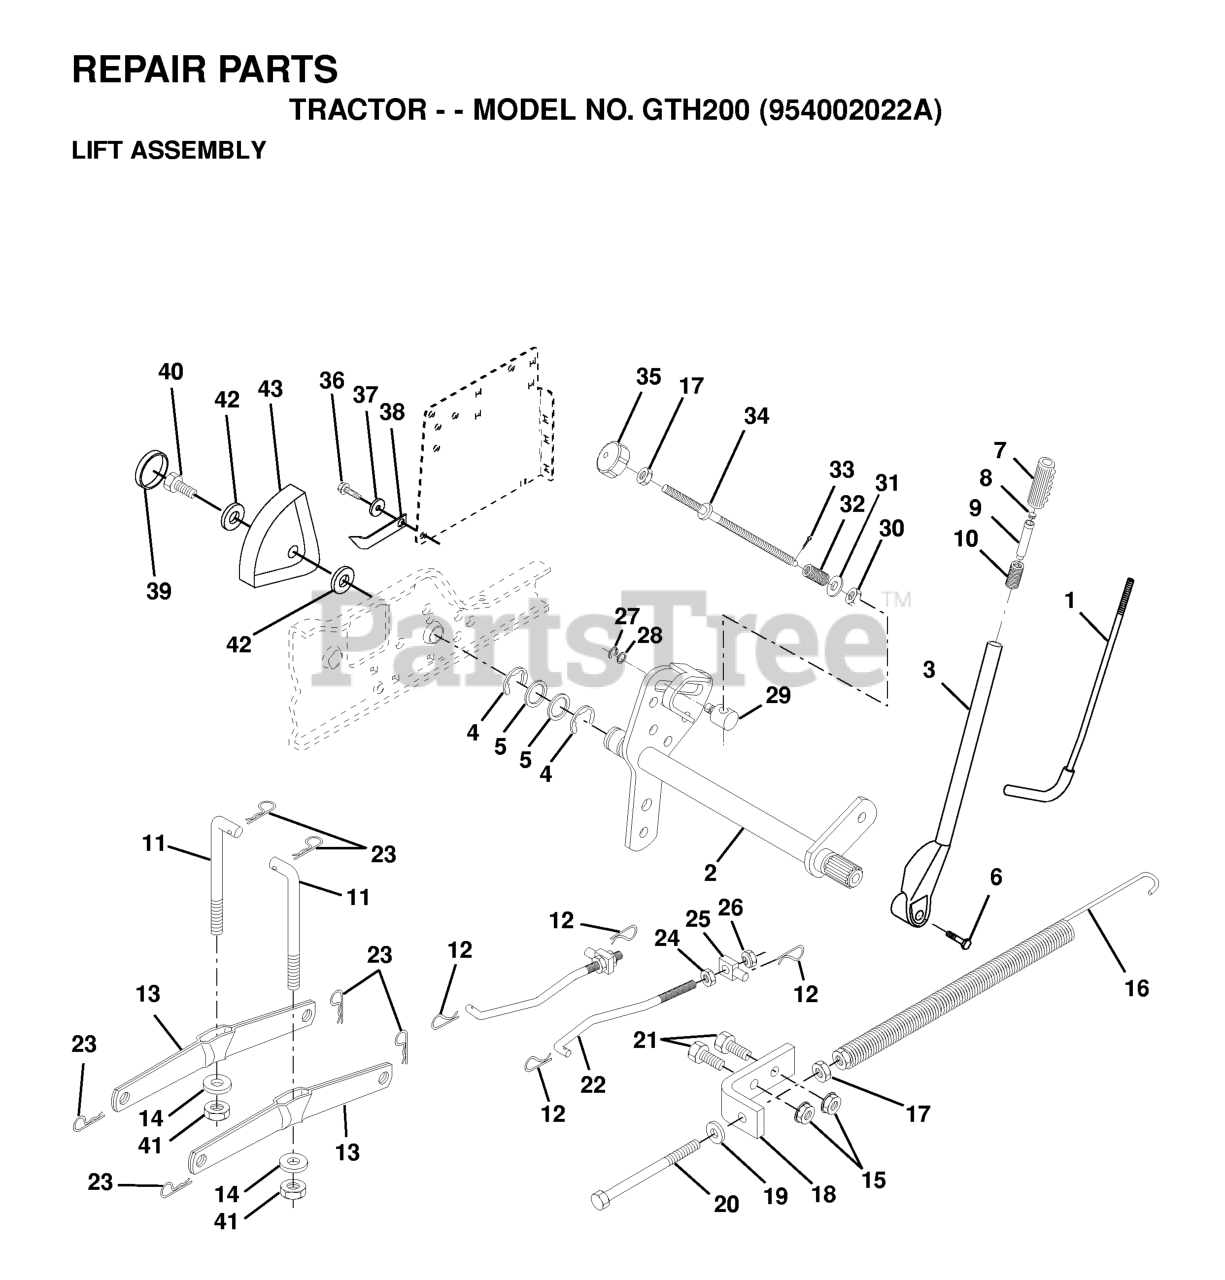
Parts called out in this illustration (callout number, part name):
1	LEVER ROD LT
2	SHAFT ASM, LIFT VGT
3	LIFT LEVER KIT
5	Washer 29/32 x 1 - 1/4 x 16 Ga.
6	BOLT
7	GRIP HANDLE
8	PLUNGER BUT KIT
9	PLUNGER BUT KIT
10	SPRING**
11	LINK LIFT
12	SPRING RETAINER
13	ARM.REAR.SUSPENSION
14	BEARING PIVOT
15	NUT
16	LIFT SPRING
17	NUT
19	WASHER
21	BOLT
22	FRONT LINK
23	RETAINER-SPRNG RB
24	NUT.HEX.JAM.1/2-13
25	TRUNION
26	NUT.LK.W/WSH.1/2.
27	Ring, Klip #T5304-37
28	Washer 15/32 x 3/4 x 16 Gauge
29	TRUNION LT
32	SPRING.COMP.INF.H
33	COTTER PIN
34	ROD.LIFT.ADJUSTABLE
35	KNOB INF 3/8-16
36	SCREW
38	POINTER HGT
40	SCREW.THDROL.5/16-18X3/4.TTY
41	NUT CROWNLOCK 3/8-24
43	HEIGHT INDICATOR
